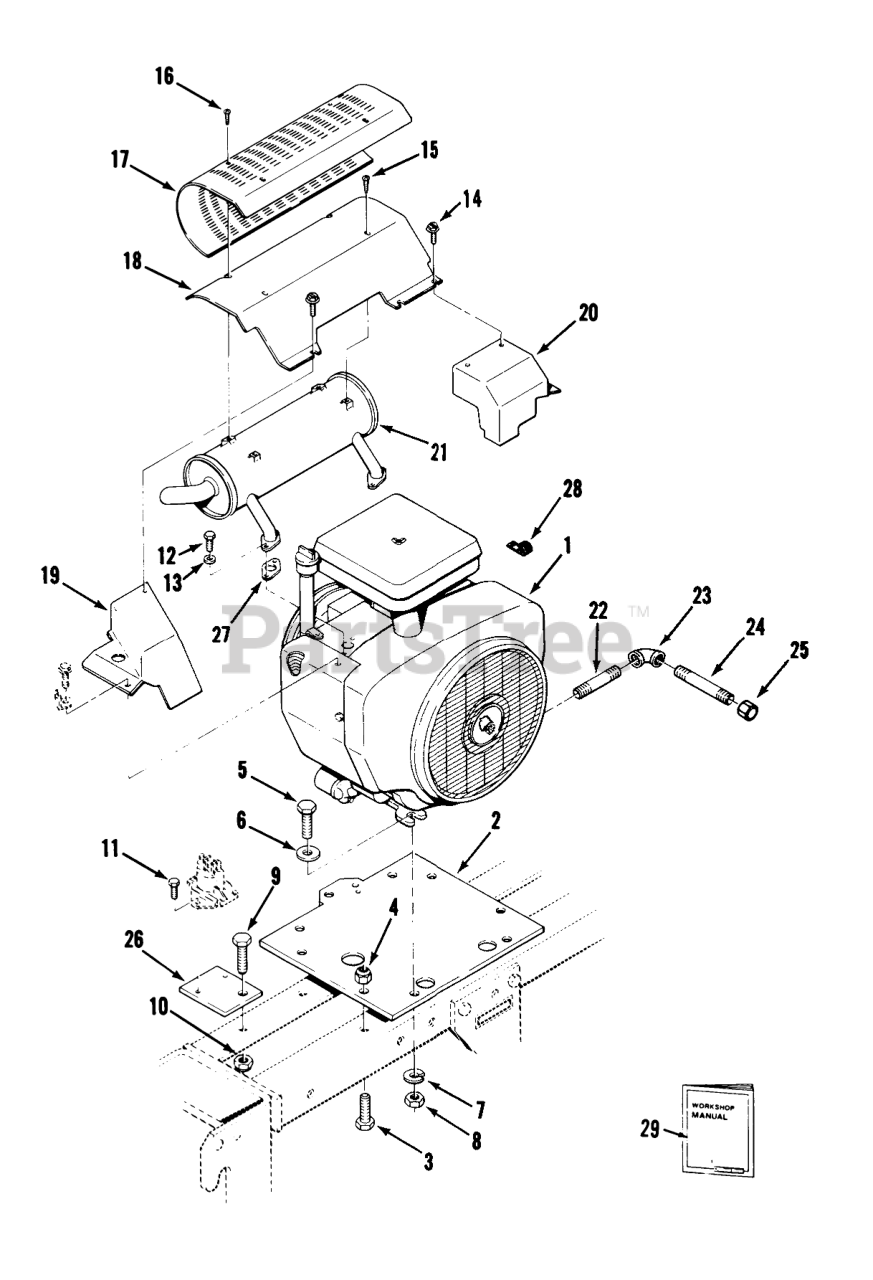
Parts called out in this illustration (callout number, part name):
1	Engine-16HP-Onan 16 HP P216-I/10538B
1	Engine-18HP-Onan 18 HP P218-I/10539B
1	Engine-20HP-Onan 20 HP P220-I/10540B
1	Engine-20HP-Onan 20 HP P220-I/10541B
2	Engine Plate
3	Bolt
4	NUT
5	BOLT
6	Washer
7	LOCKWASHER
8	Nut
9	BOLT
10	NUT
11	S.T. Bolt 1/4-20 x 1/2
12	Bolt
13	Lockwasher
14	Bolt
15	Screw
16	SCW 10-24 STAINLESS
17	SHIELD
18	Air Deflector
19	LH Exhaust Cover
20	RH Exhaust Cover
21	Muffler
21	Muffler 520-H
22	Pipe
23	ELBOW 3/8 90 DEG
24	PIPE-NIPPLE 3/8 X 4"
25	Cap
26	PLATE-RELAY MOUNT B
27	Exhaust Gasket
28	CLIP
29	Onan Performer Twin Cylinder Service Manual
